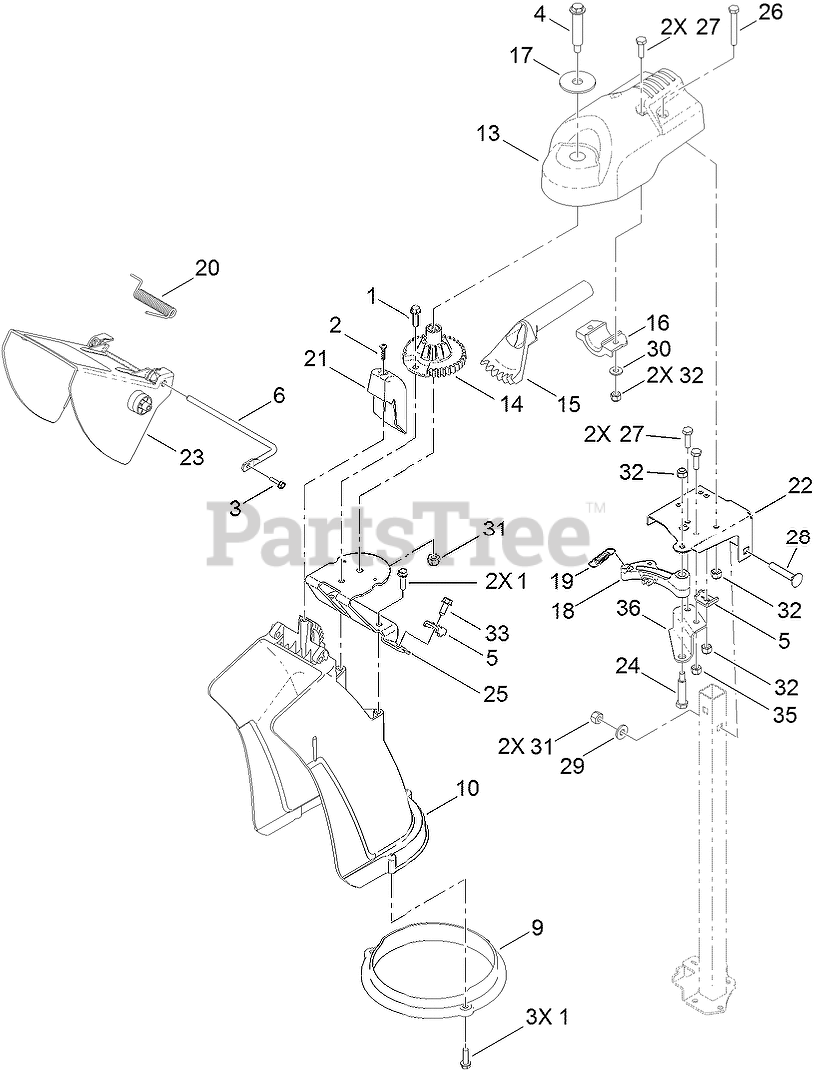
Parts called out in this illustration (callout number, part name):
1	SCREW-HWH
2	SCREW-PPH
3	SCREW-HWH
4	BOLT-SHOULDER
5	CLAMP-CABLE
6	ROD-DEFLECTOR
9	RING-CHUTE
10	CHUTE-DISCHARGE
13	MOUNT-CHUTE, DISCHARGE
14	GEAR-CHUTE
15	GEAR-BEVEL
16	MOUNT-GEAR, BEVEL
17	WASHER-FLAT
18	LATCH-CHUTE
19	SPRING-LATCH, CHUTE
20	SPRING-TORSION
21	CHUTE-COVER
22	BRACKET-SUPPORT, CHUTE
23	DEFLECTOR-CHUTE
24	BOLT-SHOULDER
25	BRACKET-MOUNT, CHUTE
26	SCREW-HH
27	SCREW-HH
28	SCREW-CARR
29	WASHER-FLAT
30	WASHER-FLAT
31	NUT-LOCK, NI
32	NUT-LOCK, NI
33	SCREW-HWH
35	NUT-LOCK, NI
36	BRACKET-SUPPORT, LATCH
